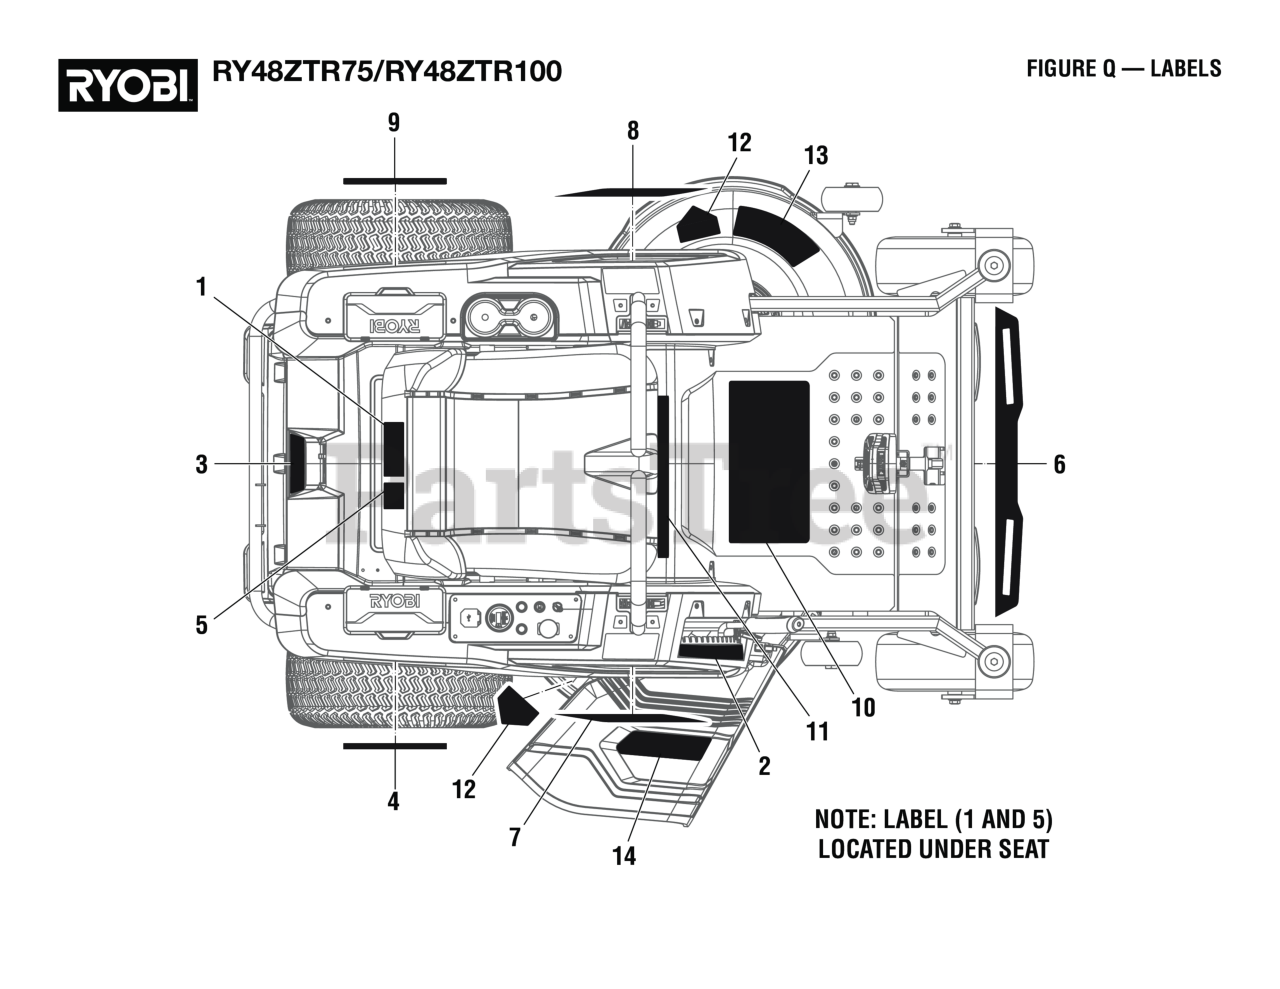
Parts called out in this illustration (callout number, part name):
1	DATA LABEL (RY48ZTR100)
2	DECK LIFT LABEL
3	CHARGING PORT LABEL, ENGLISH
3	CHARGING PORT LABEL, SPANISH
4	SUBBRAND LABEL, RIGHT (RY48ZTR100)
5	RPL LABEL, ENGLISH
5	RPL LABEL, SPANISH
6	RYOBI LABEL, FRONT
7	RYOBI LOGO, RIGHT
8	RYOBI LABEL, LEFT
9	SUBBRAND LABEL, LEFT (RY48ZTR100)
10	FLOOR DANGER LABEL, ENGLISH
11	INSTRUCTION LABEL, ENGLISH
12	No Hands CPSC Danger Label, English
13	Deck Danger Label, English
14	Discharge Danger Label, Spanish
